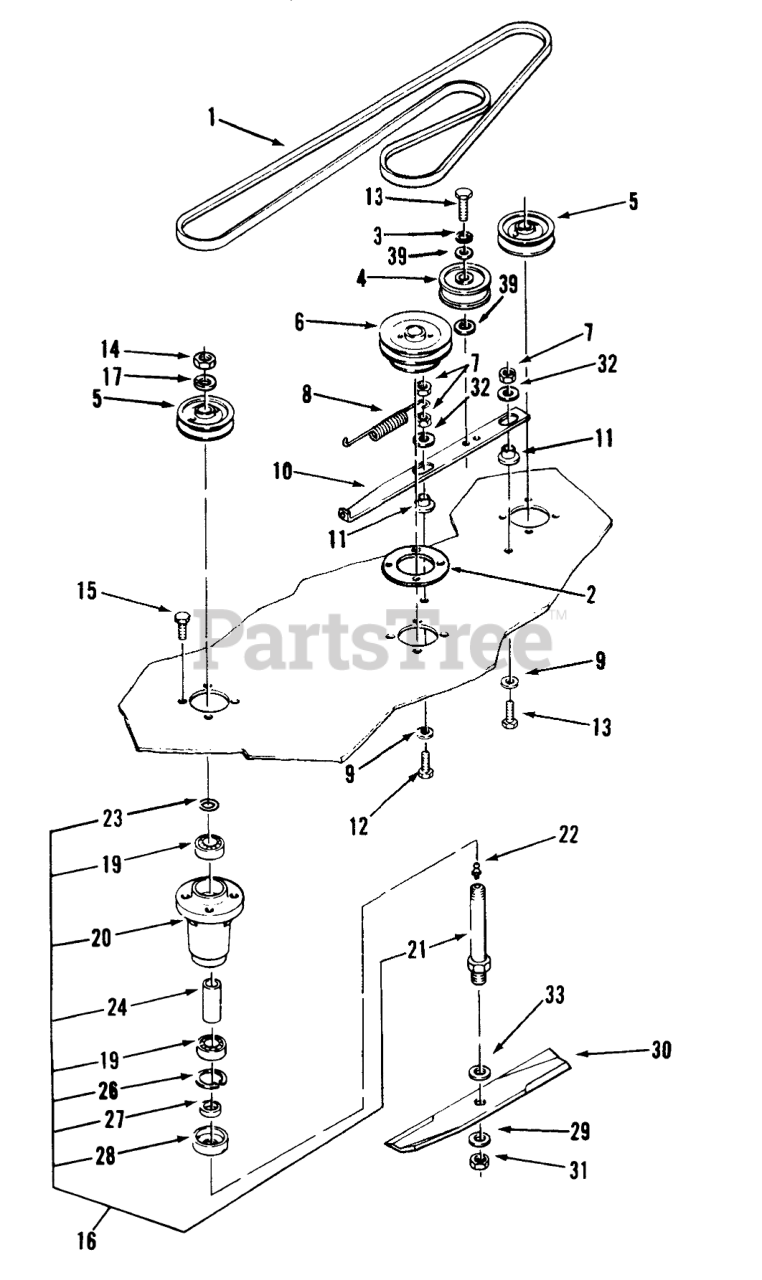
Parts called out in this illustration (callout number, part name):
1	V BELT
2	PLATE-SPINDLE
3	WASHER-LOCK
4	Idler Pulley
5	PULLEY
6	PULLEY
7	NUT-LOCK, NI
8	SPRING-EXTENSION
9	WASHER
10	BAR-IDLER SUPPORT
11	SPACER-BUSHING
12	SCREW-HH
13	SCREW-HH
14	NUT-JAM
15	SCREW-HH
16	Spindle Assembly (Incl. Ref. #19-28)
17	WASHER-LOCK
19	BEARING-BALL
20	HOUSING-SPINDLE
21	SHAFT-SPINDLE
22	FITTING-GREASE
23	O RING
26	RING-RETAINING
27	SPACER-BLADE
28	CUP-SPINDLE
29	WASHER-FLAT
30	14IN BLADE KIT
31	NUT-JAM
32	WASHER
33	Washer
